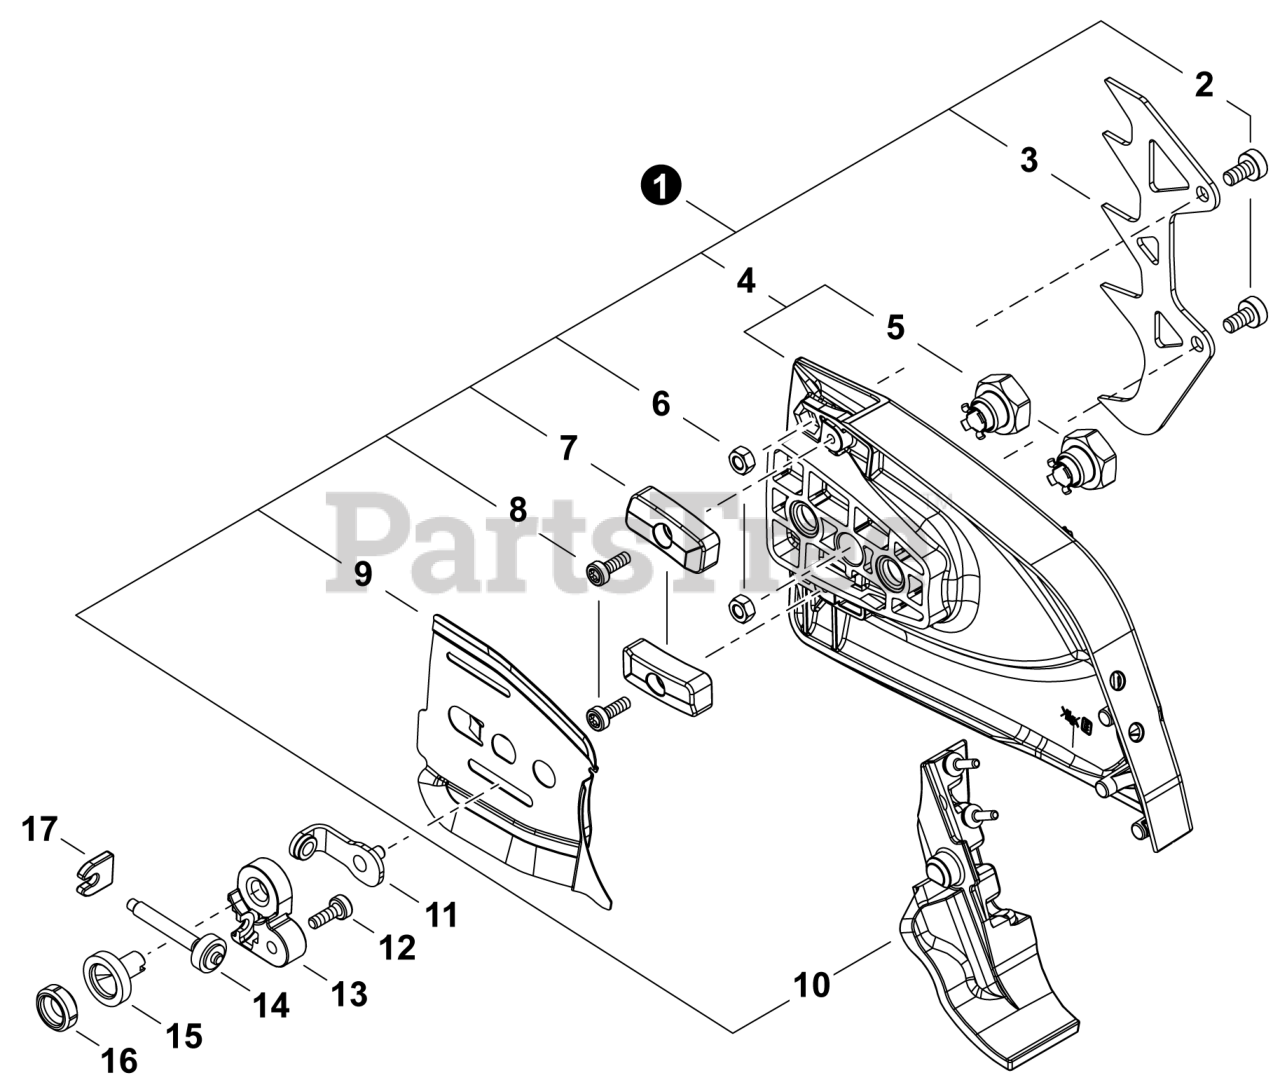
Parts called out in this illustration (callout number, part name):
1	SPROCKET GUARD ASSY
2	BOLT, TORX 5x10
3	SPIKE, BUMPER
4	GUARD, SPROCKET
6	NUT, LOCK M5
7	PLATE, FRICTION
8	BOLT, TORX 4x12
9	PLATE, GUIDE - INNER
10	CUSHION
11	TENSIONER, CHAIN
12	BOLT, TORX 4x12
13	COLLAR 8
15	GEAR, WORM
16	COLLAR 10
17	GUIDE, SHAFT
